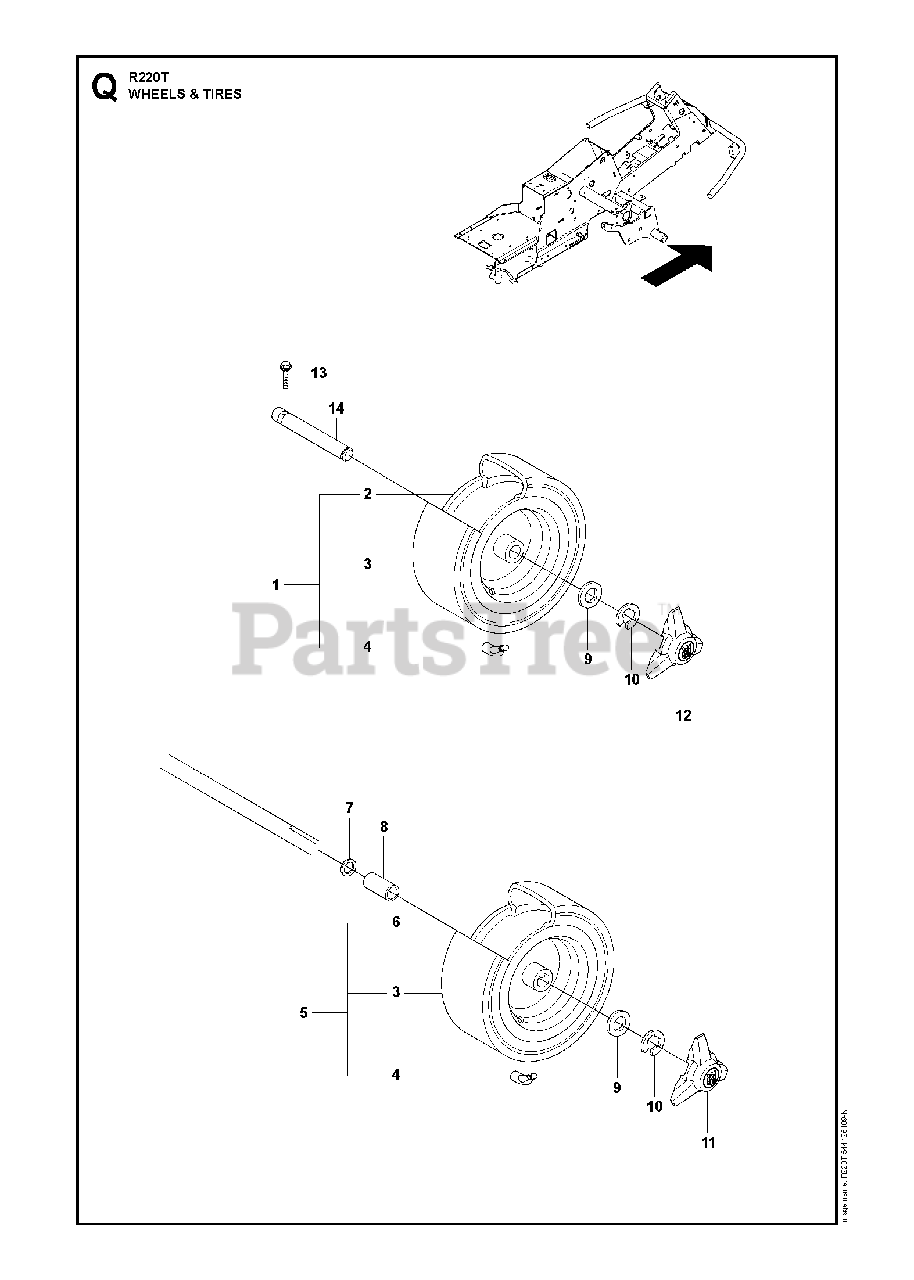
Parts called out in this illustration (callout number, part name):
3	TIRE
4	VALVE
8	SPACE SLEEVE
10	RETAINING RING
13	BOLT FLANGE - M8X40\
